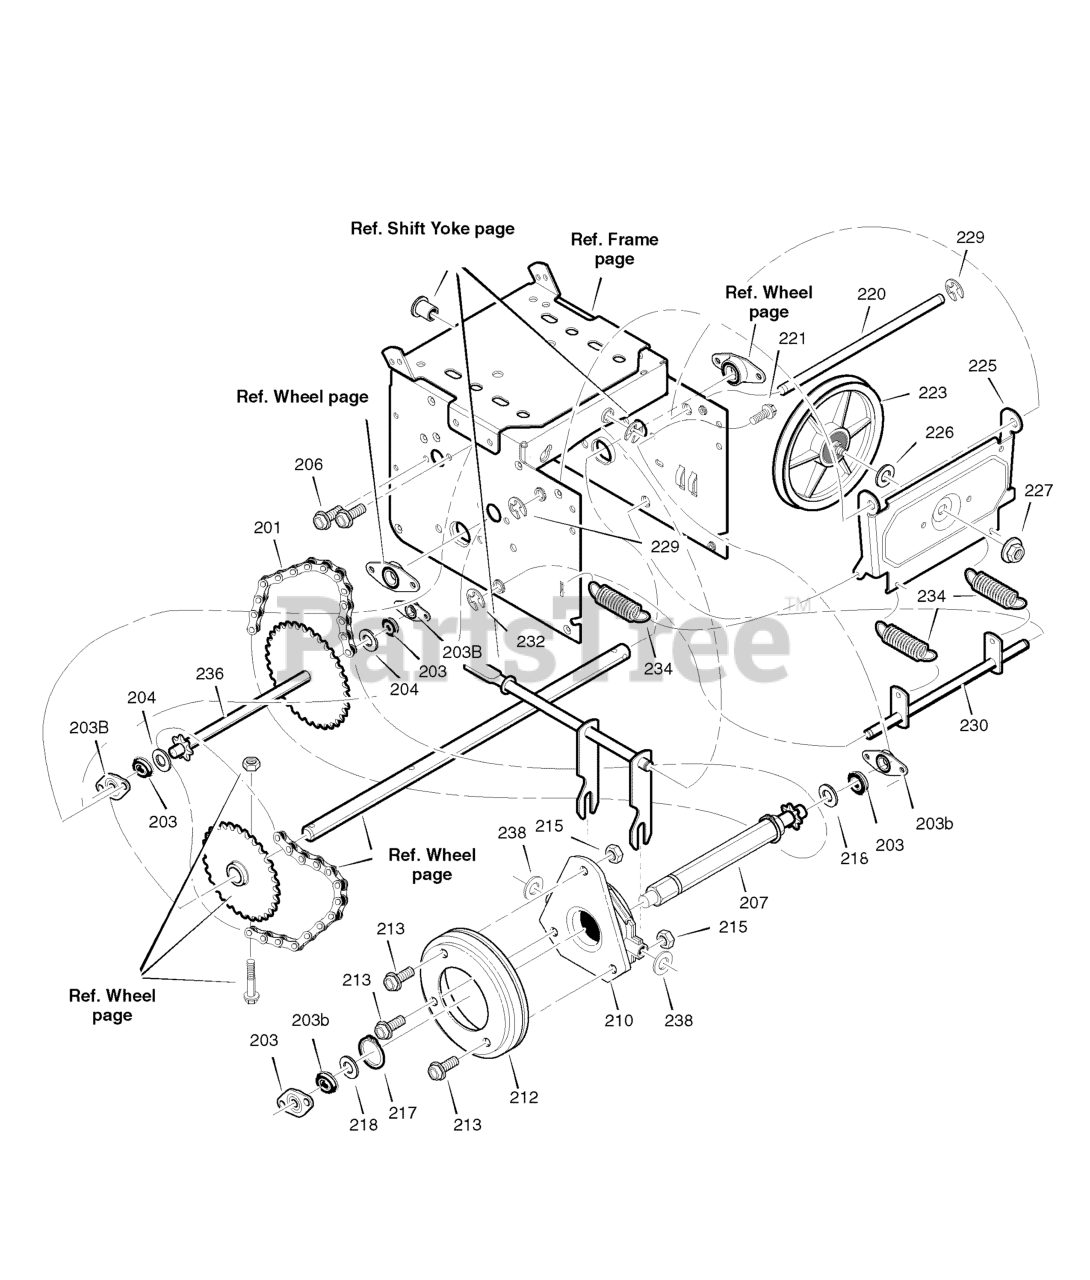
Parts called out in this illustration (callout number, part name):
200	LF AXLE, SWING PLATE YZ
201	CHAIN, ROLLER #420x19.00
203	BALL BEARING
206	SCREW, TAP 5/16-18 x 0.5
207	ASSY, HEX SHAFT
208	CHAIN, ROLLER #420x18.00 LG
210	BEARING, TRUNION CLUTCH R
212	WHEEL, FRICTION DISC
215	NUT, KEPS HEX 1/4-20
217	RING, RETEXT
221	SCREW, TAP 5/16-18 x .5
223	FRICTION PULLEY
225	LF PLATE, SWINGING YZ
226	SPACER, FRICTION PULLEY
227	NUT, FLANGE LOCK 3/8-24
229	RETAINER, RING
230	SPRING LINK ASSEMBLY
232	RETAINER, RING
234	SPRING, EXTENSION
236	WLD, INTERMED SPROCKET 33T/7
238	WASHER, FLAT
